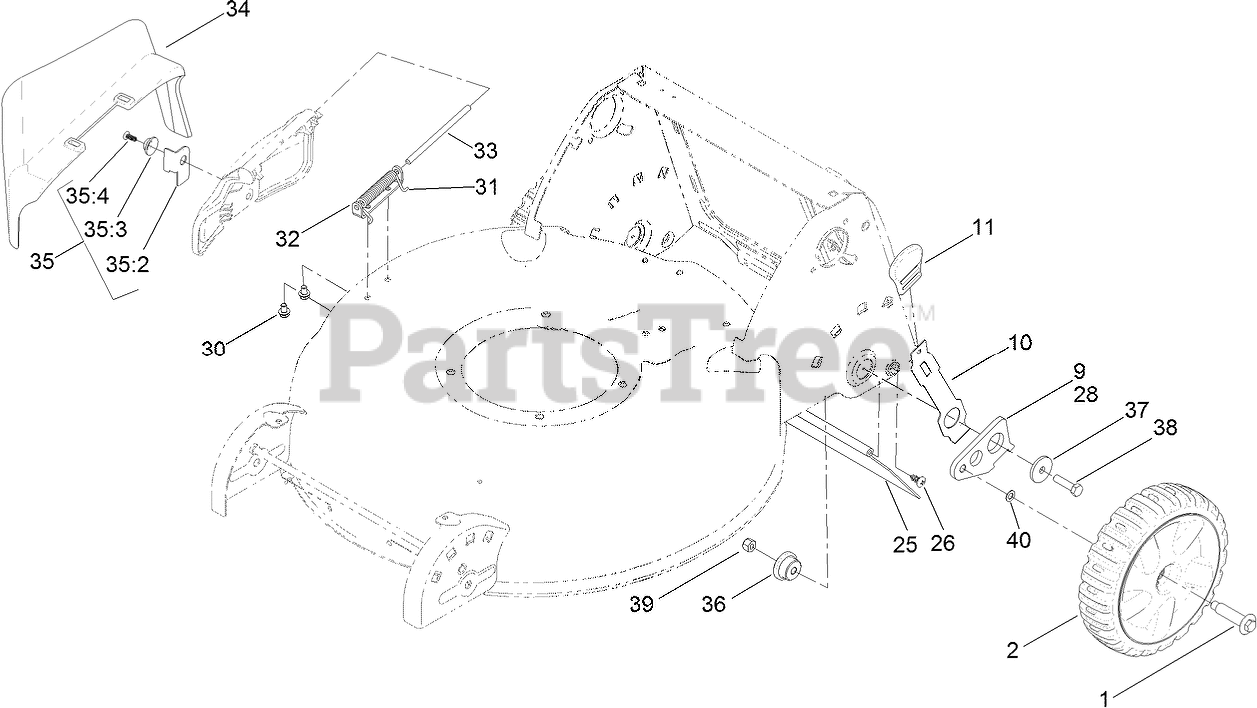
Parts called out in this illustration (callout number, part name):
1	BOLT-SHOULDER
2	8 INCH WHEEL AND TIRE ASM
9	ARM-REAR PIVOT, LH
10	ARM-SPRING, REAR
11	KNOB-HOC
25	SHIELD-TRAILING
26	SCREW-PTH
28	ARM-REAR PIVOT, RH
30	SCREW-HWH
31	SPRING-TORSION
32	BRACKET-COVER
33	ROD-COVER
34	CHUTE-DISCHARGE, SIDE
35	DISCHARGE DOOR ASM
35:2	LATCH-DOOR
35:3	CAP-DOOR
35:4	SCREW-PLASTITE
36	Bushing-Mount, HOC
37	Washer-Flat
38	SCREW-HH
39	NUT-LOCK, NI
40	WASHER
